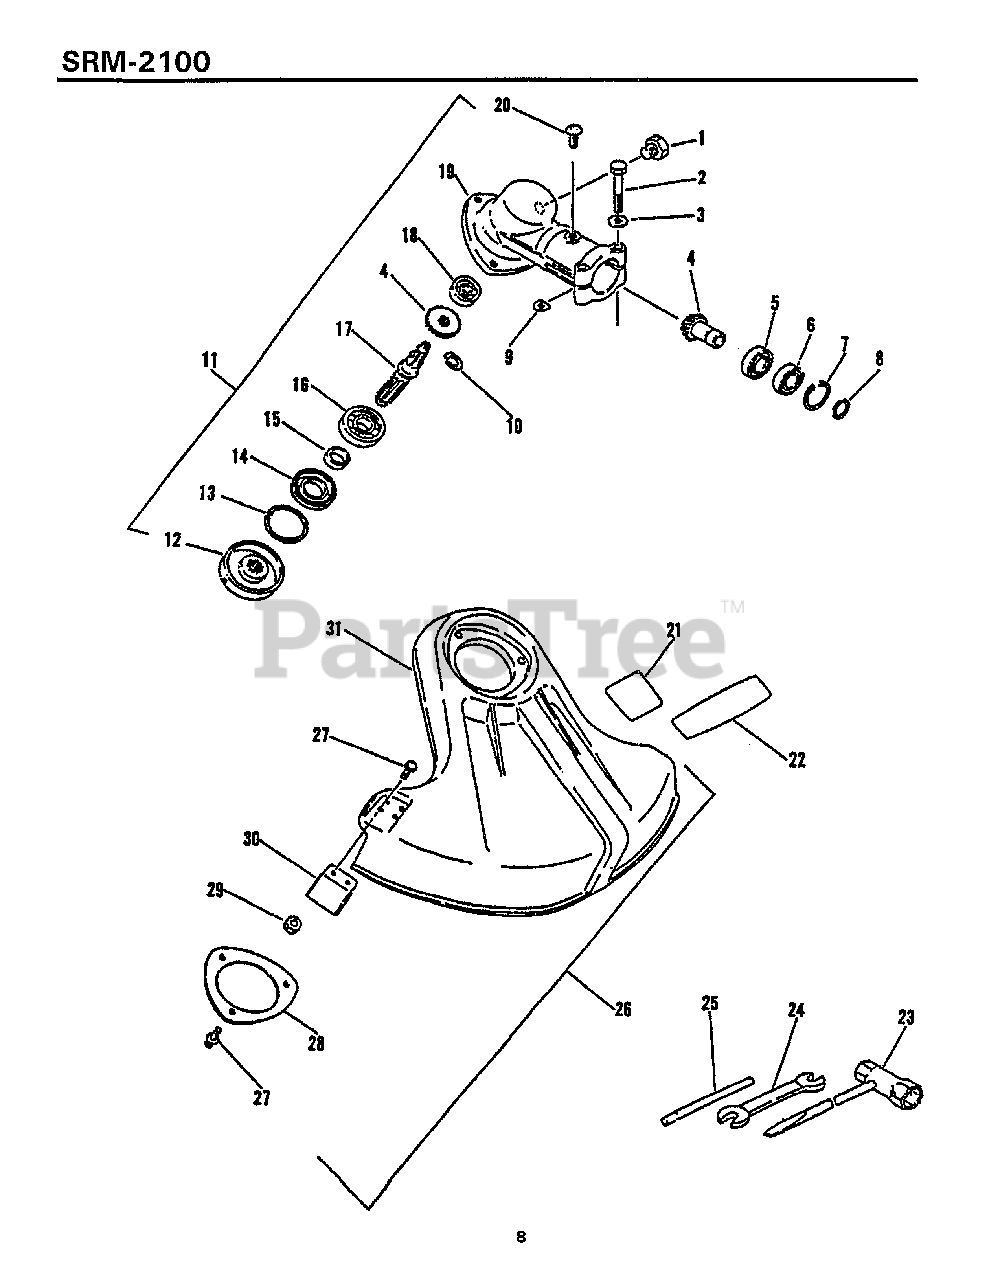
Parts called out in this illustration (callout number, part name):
1	BOLT 8×8 SP
2	BOLT 5×35 SP
3	WASHER, FLAT 5.5×10×0.8
4	GEAR SET
5	BEARING, BALL 6900
6	BEARING, BALL 6900Z
7	RING, SNAP Ø22
8	RING, SNAP Ø12
10	RING, SNAP Ø10
11	GEAR CASE ASSY
12	PLATE, ADAPTOR - UPPER
13	RING, SNAP Ø32
14	SEAL, OIL 22
15	SPACER 11.8×15×9
16	BEARING, BALL 6201
17	SHAFT, GEAR
18	BEARING, BALL 609
19	HOUSING, GEAR CASE
20	SCREW 5×10
21	LABEL, CAUTION
22	LABEL, ECHO
23	T-WRENCH
24	SPANNER 8×10
25	TOOL, LOCKING 5×120 MM
26	DEBRIS SHIELD ASSY
27	SCREW 5×16
28	BRACKET, SHIELD
29	NUT M5
30	CUTTER, LINE
31	SHIELD, DEBRIS
